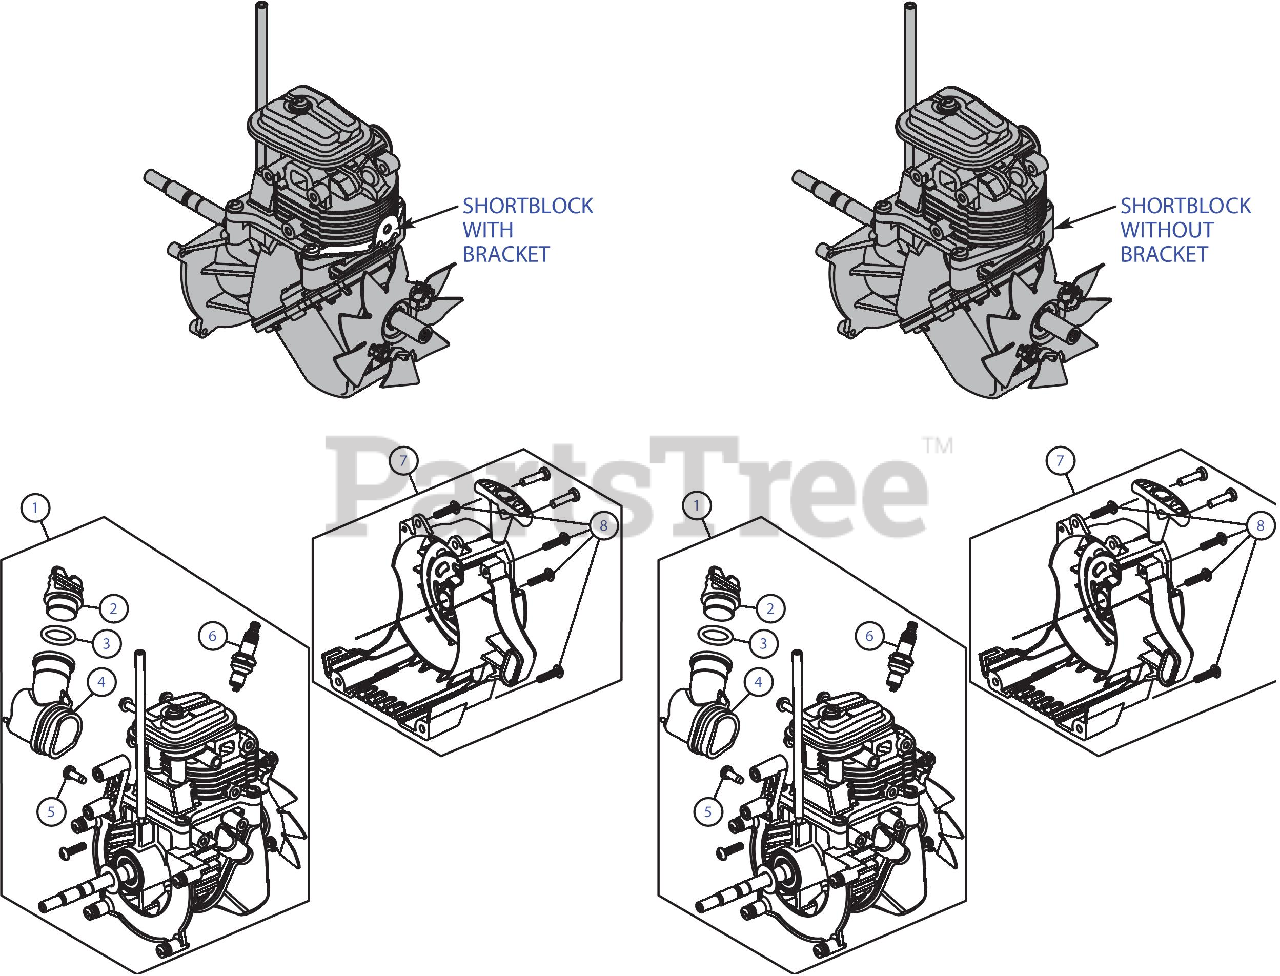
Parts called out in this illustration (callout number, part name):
1	Shortblock Assembly (With Bracket)
1	Shortblock Assembly (Without Bracket)
2	Oil Fill Plug
3	O-Ring
4	Oil Fill Tube
5	Screw
6	Spark Plug
7	Starter Housing Assembly (includes 8) (With Bracket)
7	Starter Housing Assembly (includes 8) (Without Bracket)
